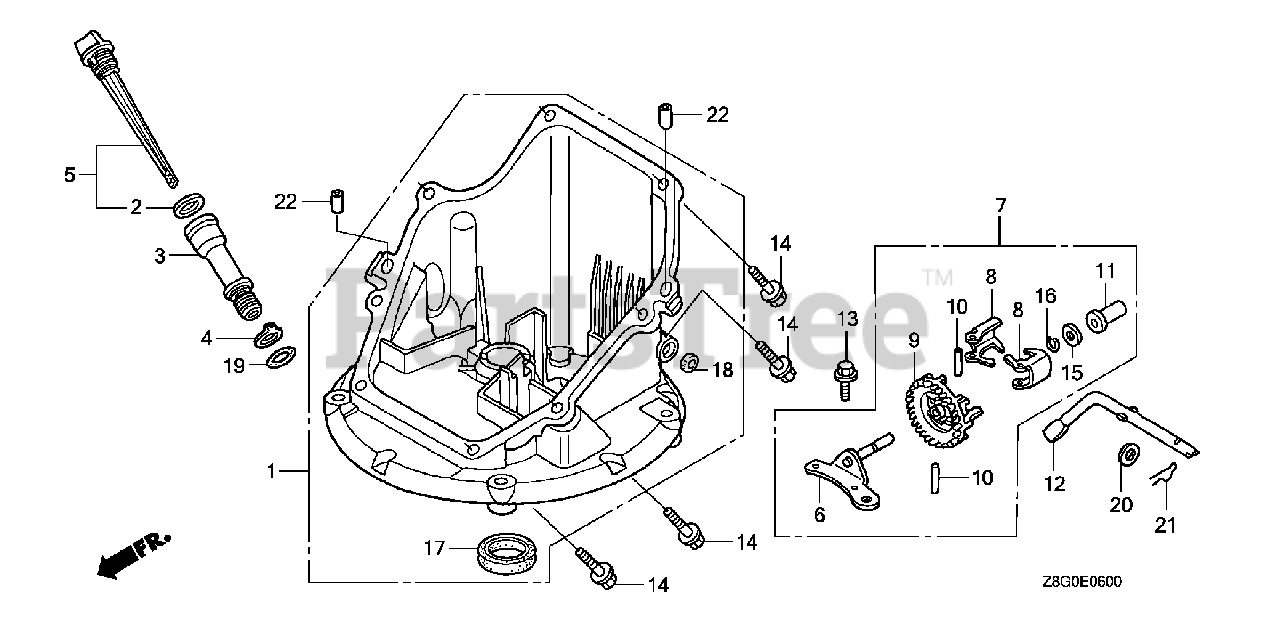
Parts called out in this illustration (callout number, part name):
1	PAN ASSY., OIL
2	GASKET, OIL FILLER CAP
3	EXTENSION, OIL FILLER
4	WASHER, EXTENSION LOCK
5	GAUGE ASSY., OIL LEVEL
6	SHAFT, GOVERNOR HOLDER
7	GOVERNOR ASSY.
8	WEIGHT, GOVERNOR
9	HOLDER, GOVERNOR WEIGHT
10	PIN, GOVERNOR WEIGHT
11	SLIDER, GOVERNOR
12	SHAFT, GOVERNOR ARM
13	BOLT, FLANGE (6X14) (CT200)
14	BOLT, FLANGE (6X25) (CT200)
15	WASHER, THRUST (6MM)
16	CLIP, GOVERNOR HOLDER
17	OIL SEAL (28X41.25X6)
19	O-RING (14.8X2.4) (NOK)
20	WASHER, PLAIN (6MM)
21	PIN, LOCK (8MM)
22	PIN, DOWEL (8X20)
